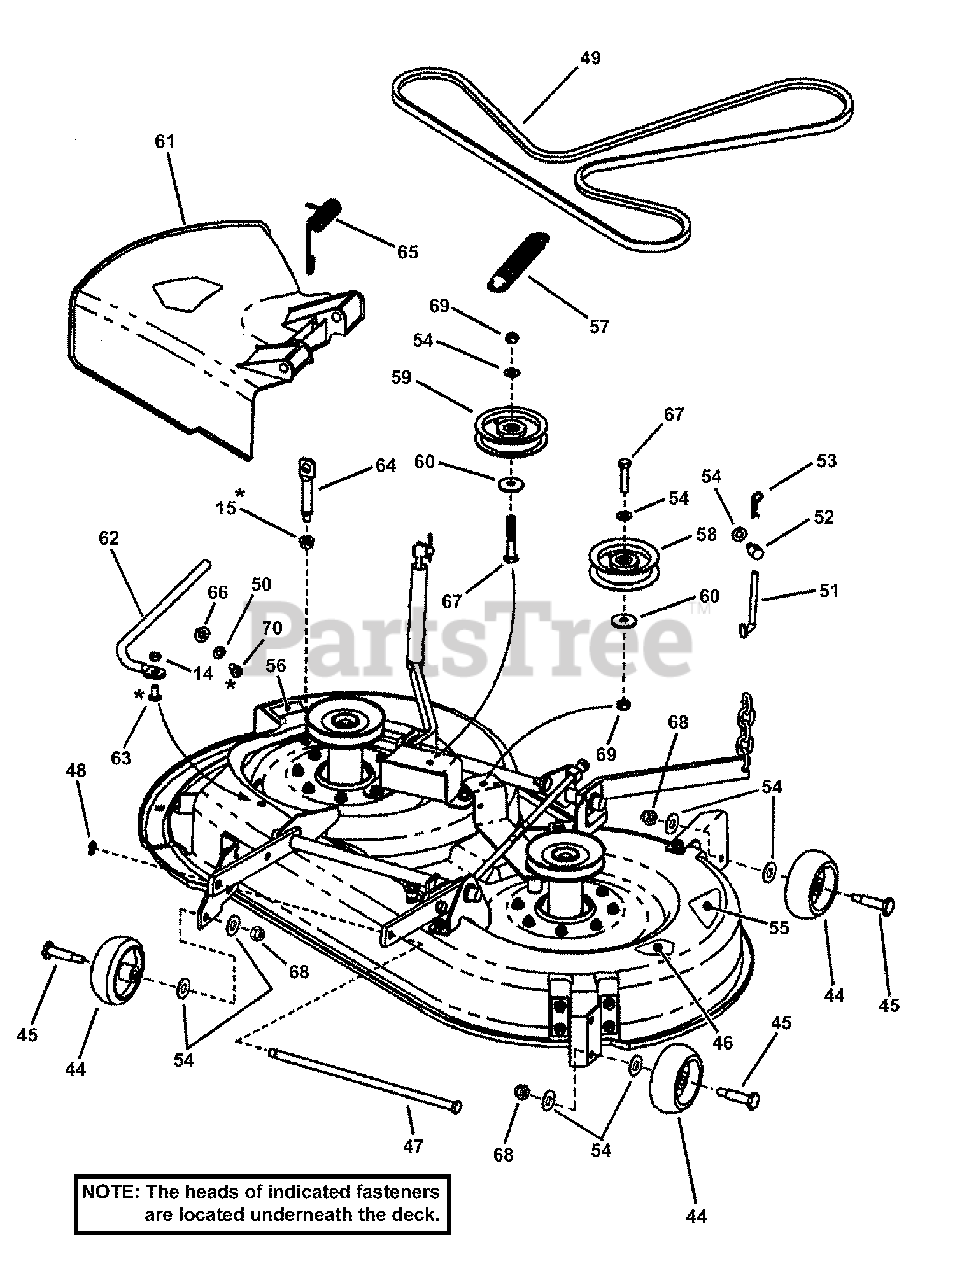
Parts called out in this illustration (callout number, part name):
14	NUT, 5/16-18 Hex Center Lock, GR5 or B
15	NUT, 3/8-16 Hex Flange Lock
44	WHEEL, 4 x 1-1/2" Offset
45	BOLT, 3/8-24 x .62 Shoulder
46	DECAL, Danger, Cut Finger (CPSC)
47	ROD, Deck Support
48	RING, .438 External Retaining
49	V-BELT, HA Section 89.8" Effective Length
50	WASHER, .34 x .69 x .08 Flat
51	ADJUSTER, Chain (5/16-18 thread)
52	SWIVEL, Adjustment
53	HAIR PIN, 3/32 x 1-1/2"
54	WASHER, 3/8" SAE Flat
55	DECAL, 38 Inch
56	DECAL, Chute/Deflector
57	SPRING, Extension 1.03 Dia. X 6.8" long
58	IDLER, 3-1/4" I.D. x 1-1/4" Flat
59	PULLEY, 3-1/4 Dia. Flat Idler
60	WASHER, Cone
61	CHUTE, Discharge, 38" Deck
62	ROD, Pivot, Side Discharge, 38
63	BOLT, 5/16-18 x 3/4" Short Neck Carriage, GR5
64	ROD, Mounting, Side Discharge
65	SPRING, Torsion-Side Discharge-38 Deck
66	TEENUT, 5/16-18 Thread
67	SCREW, 3/8-16 x 1-3/4" Hex Head Cap, GR5
68	NUT, 3/8-24 Hex Center Lock
69	NUT, 3/8-16 Hex Center Lock, GR5 or B
70	SCREW 5/16-18 x 5/8" Cross Recessed Pan Head
